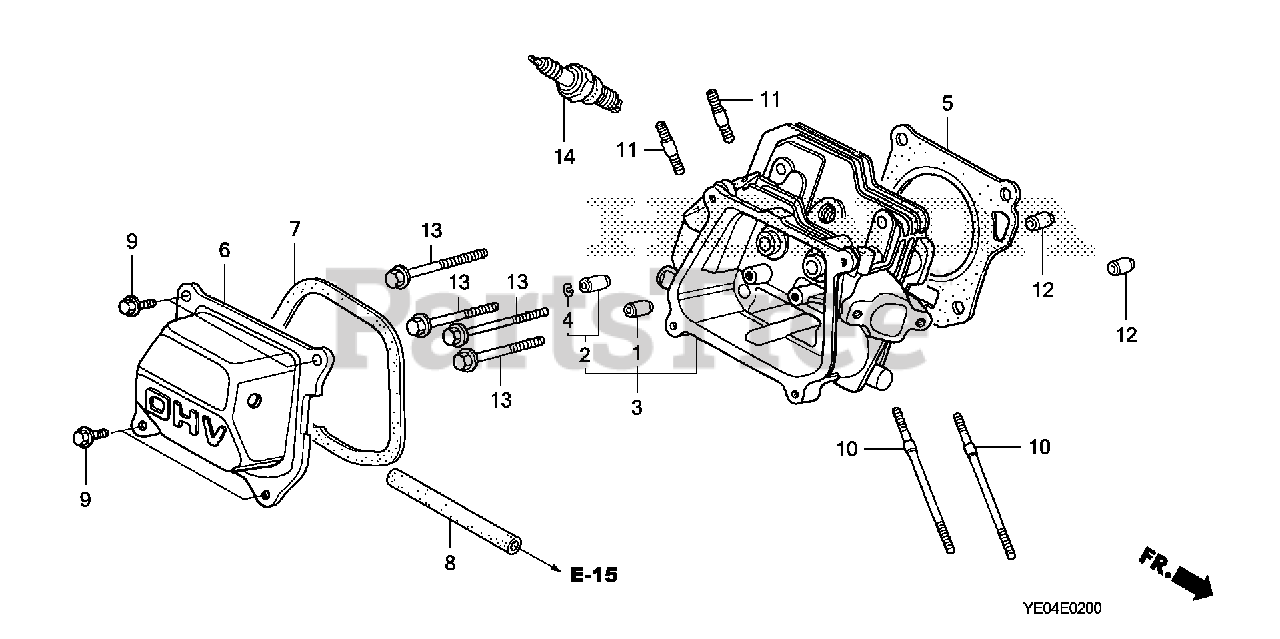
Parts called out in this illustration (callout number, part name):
1	GUIDE, VALVE (OVER SIZE)
2	GUIDE, EX. VALVE (OVER SIZE)
3	CYLINDER HEAD
4	CLIP, VALVE GUIDE
5	GASKET, CYLINDER HEAD
6	COVER, HEAD
7	GASKET, HEAD COVER
8	TUBE, BREATHER
9	BOLT, FLANGE (6X12) (CT200)
10	BOLT, STUD (6X112)
11	BOLT, STUD (8X32)
12	PIN, DOWEL (10X16)
13	BOLT, FLANGE (8X60)
14	SPARK PLUG (BPR5ES) (NGK)
14	SPARK PLUG (BPR6ES) (NGK)
